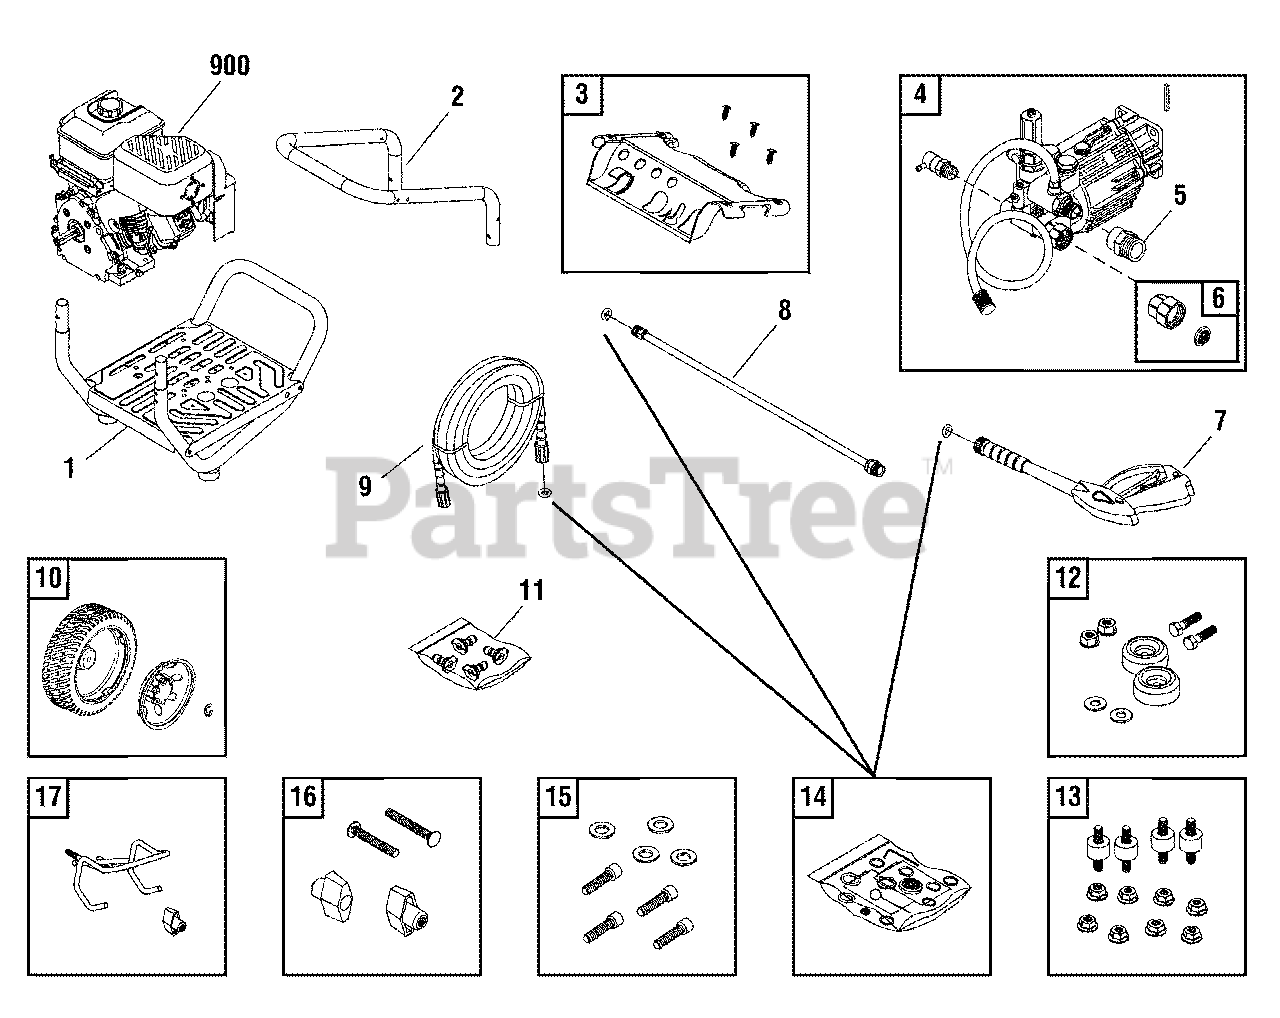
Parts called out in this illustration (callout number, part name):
6	CONNECTOR, Garden Hose
8	EXTENSION, QC
11	KIT, QC Nozzles
12	MOUNT, Vibration
13	KIT, Vibration Mount
15	KIT, Hardware, Pump Mounting
16	KIT, Hardware, Handle
900	* ENGINE
